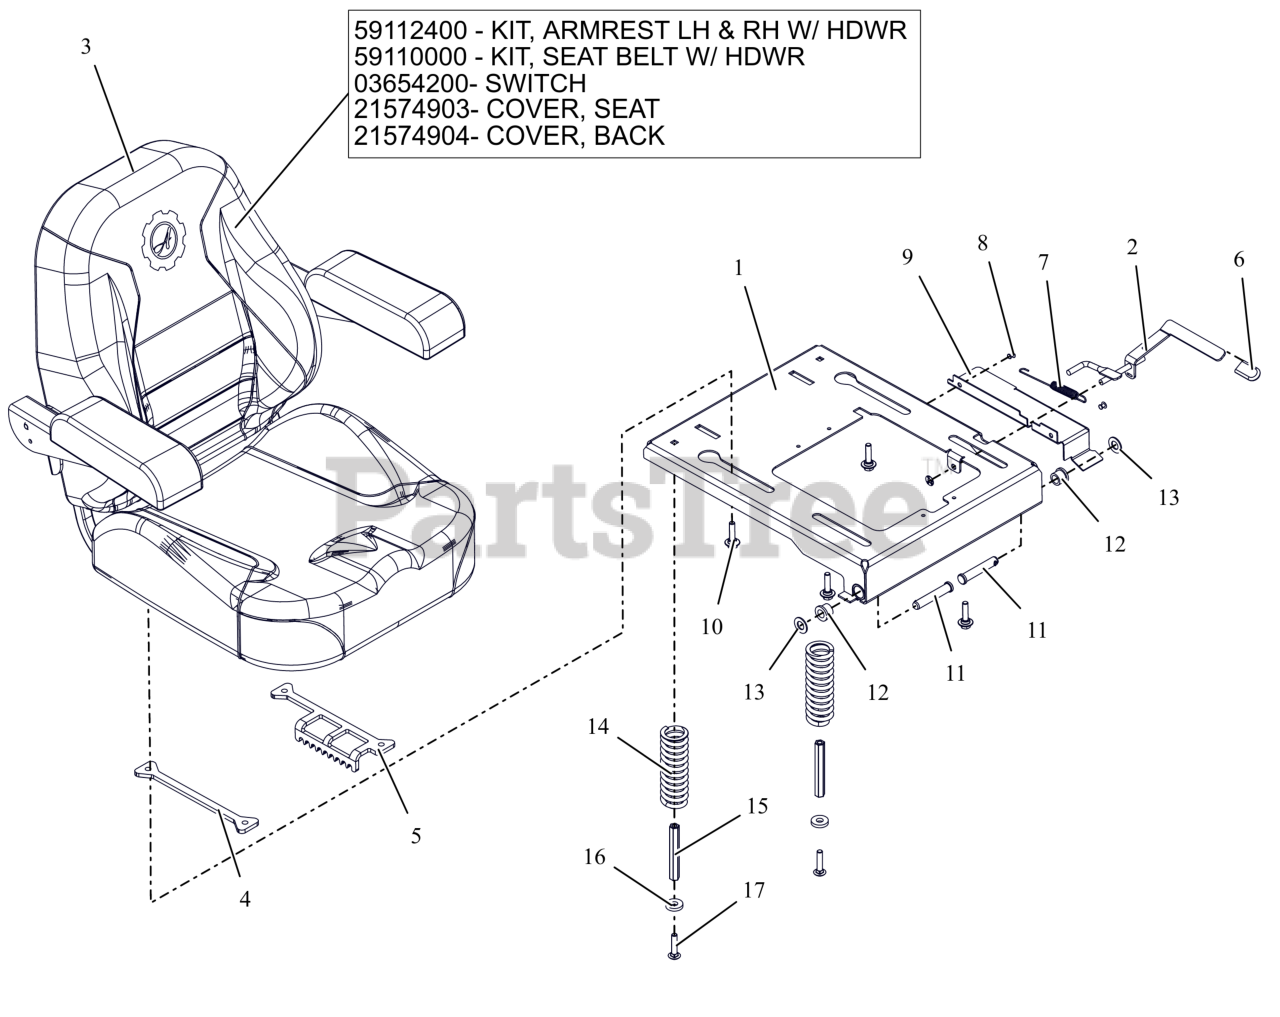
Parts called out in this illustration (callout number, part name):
1	WLDMT, SEAT PLATE HD
2	WLDMT, SEAT SLIDE LEVER
3	SEAT, APEX
3	KIT-LH & RH ARM REST-05124700
3	KIT-SEAT BELT REPLACE-05007300
3	SWITCH- SEAT
3	KIT, SEAT COVER - APEX
3	KIT, BACK COVER - APEX
4	PLATE, ADJUSTABLE
5	PLATE, HD SEAT ADJUSTMENT
6	GRIP, SEAT LEVER, GREY
7	SG-TENS .06X.482X5.35
8	RIVET, .1875 AL/AL .126-.250
9	GUARD, SEAT PLATE CE
10	BOLT SHLDR .31-18 X .175
11	PIN-CLIC .50X2.70X2.31 -ZCC
12	BSHG, FLG .516X.750X.625X.937
13	WSHR, FLT .531X1.00X.063 ZCC
14	SPRING, COMPRESSION SEAT 224LB
15	NUT, COUPLING 5/16X18 X 3.75
16	WSHR, FLT .406X1.00X.188 ZCC
17	BLT,RHSN .31-18X1.50 G5 ZCC
